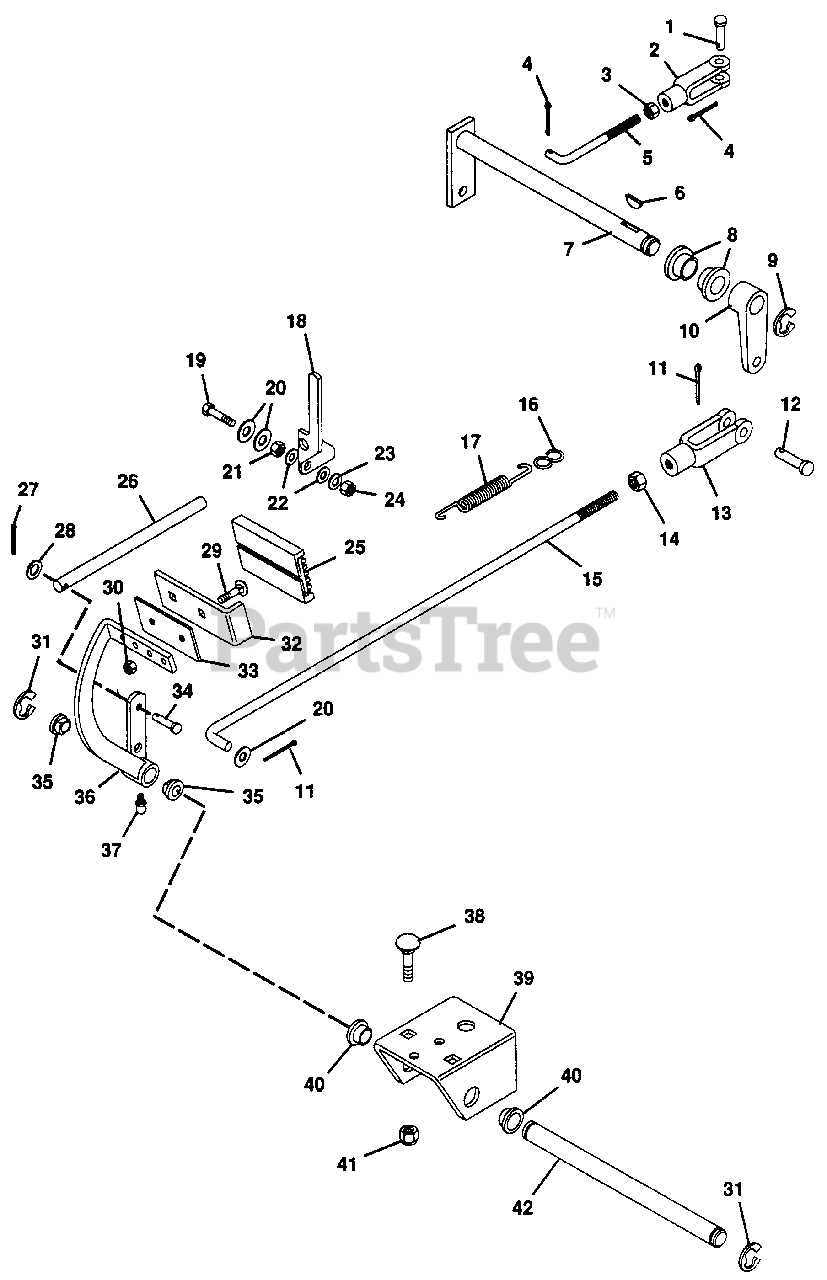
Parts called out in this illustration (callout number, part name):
1	PIN, CLEVIS 5/16X.812
2	YOKE
3	NUT, HEX 5/16-24
4	PIN, COTTER .09X.75
5	ROD, PARKING BRAKE
6	KEY, WOODRUFF .187X.75 HRD #9
7	WELDMENT, BRAKE CROSS SHAFT
8	BUSHING, NYLON .76X1.00X.76 FLG
9	E-RING, .750 SHAFT
10	LEVER, PTO
11	PIN, COTTER .125X.75
12	PIN, CLEVIS .375X.948
13	CLEVIS, 3/8-24 ADJUSTABLE
14	NUT, JAM 3/8-24
15	ROD, BRAKE
16	CLIP, SPRING
17	SPRING, EXT. 5.50X.50X20 RATE
18	ARM, PARKING BRAKE LOCK
19	BOLT, HEX 3/8-16X1.25
20	WASHER, FLAT .406X.812X.065
21	NUT, JAM 3/8-16 HEX
22	WASHER, NYLON .375X.75X.06
23	WASHER, LOCK 3/8
24	NUT, LOCK 3/8-16
25	PAD, PEDAL
26	ROD
27	PIN, COTTER .06X.75
28	WASHER, FLAT .281X.625X.065
29	BOLT, CARRIAGE 1/4-20X1.25
30	NUT, LOCK 1/4-20
31	E-RING, .625 SHAFT
32	PEDAL, BRAKE
33	PLATE, BRAKE
34	PIN, CLEVIS .25X1.03
35	BEARING
36	WELDMENT, BRAKE PEDAL
37	FITTING, LUBE 1/4-28
38	BOLT, CARRIAGE 3/8-16X.75
39	BRACKET, BRAKE PEDAL
40	BUSHING, NYLON .63X.873X.50
41	NUT, LOCK 3/8-16
42	SHAFT, BRAKE PEDAL MOUNTING
